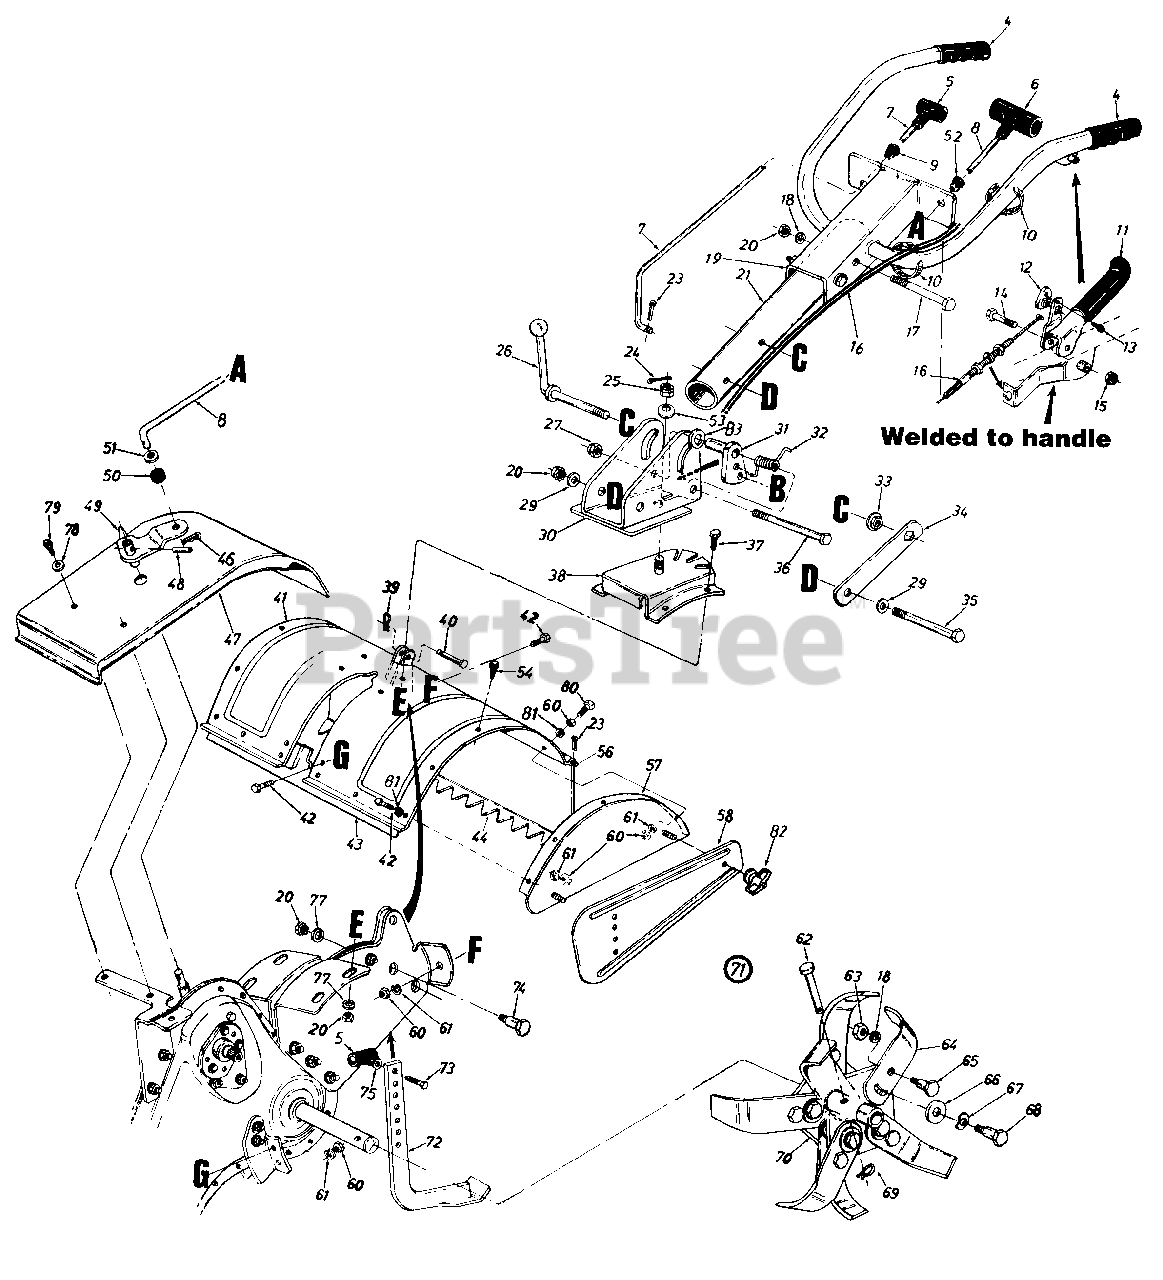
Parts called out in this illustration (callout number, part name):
4	Handle Grip
5	Small "T" Knob
6	Large "T" Knob
7	Clutch Rod
8	Control Rod 37" Lg.
9	Snap On Bushing 3/8" Dia.
10	Cable Tie-Self Clinching
12	Barrel Cable Hold Down
13	Hex B-Tap Scr. #10 x .44" Lg.
14	Hex Bolt 3/8-24 x 2.25" Lg.
15	Hex Jam L-Nut 3/8-24 Thd.
16	Clutch Control Cable 46" Lg.
17	Hex Bolt 3/8-16 x 3.00" Lg.
18	L-Wash. 3/8" I.D.- H.D.
24	Cotter Pin 3/32" Dia. x 1.25" Lg.
25	Hex Slotted Nut 5/8-18 Thd.
26	Handle Adj. Crank
27	Hex Cent. L-Nut 3/8-16 Thd.
29	Bell-Wash. .4" I.D. x .87" O.D.
32	Spring Handle Adj. (Torsion)
33	Hex Flange Nut 3/8-24 Thd.
34	Bracket Hex Nut Retainer
35	Hex Bolt 3/8-16 x 3.25" Lg.
36	Hex Bolt 3/8-16 x 3.00" Lg.- Gr. 8
37	Hex Bolt 3/8-16 x 1" Lg.
40	Clevis Pin .375" Dia.
43	Bracket Reinforcement - 18"
46	Intern. Cotter Pin 5/16" Dia.
49	Shifting Crank Ass'y.
50	Rubber Washer.33" I.D.
51	Fl-Wash. .4" I.D. x 1.25" O.D.
52	Snap On Bushing 1/2" Dia.
53	Bell-Wash..63" I.D. x 1.25"
54	Hex Wash. Tap Scr.
56	Tiller Flap Rod
60	Hex Nut 5/16-18 Thd.
61	L-Wash. 5/16" I.D.
62	Clevis Pin .375" Dia.
63	Hex Nut 3/8-24 Thd.
65	Shld. Bolt 1/2" Dia. x .175
66	Fl-Wash. .51" I.D. x 1.50"
67	Bell-Wash. .515" I.D. x 1.14"
68	Shld. Bolt 1/2" Dia. x .320
69	Intern. Cotter Pin
73	Hex Bolt 3/8-16 x 1" Lg.
74	Shld. Bolt 1/2" I.D. x .62" Lg.
75	Fl-Wash. 3/8" I.D. x 5/8" O.D.
77	L-Wash. 3/8" I.D.
78	Fl-Wash. .281" I.D. x .62"
79	Hex Wash. Self-Tap Scr. 1/4-20 x .50" Lg.
80	Hex Bolt 5/16-18 x 11/4" Lg.
81	Cap L-Nut 5/16-18 Thd.
82	Plastic Knob 5/16-18 Thd.
83	Fl-Wash. .406" I.D. x .875" O.D.
